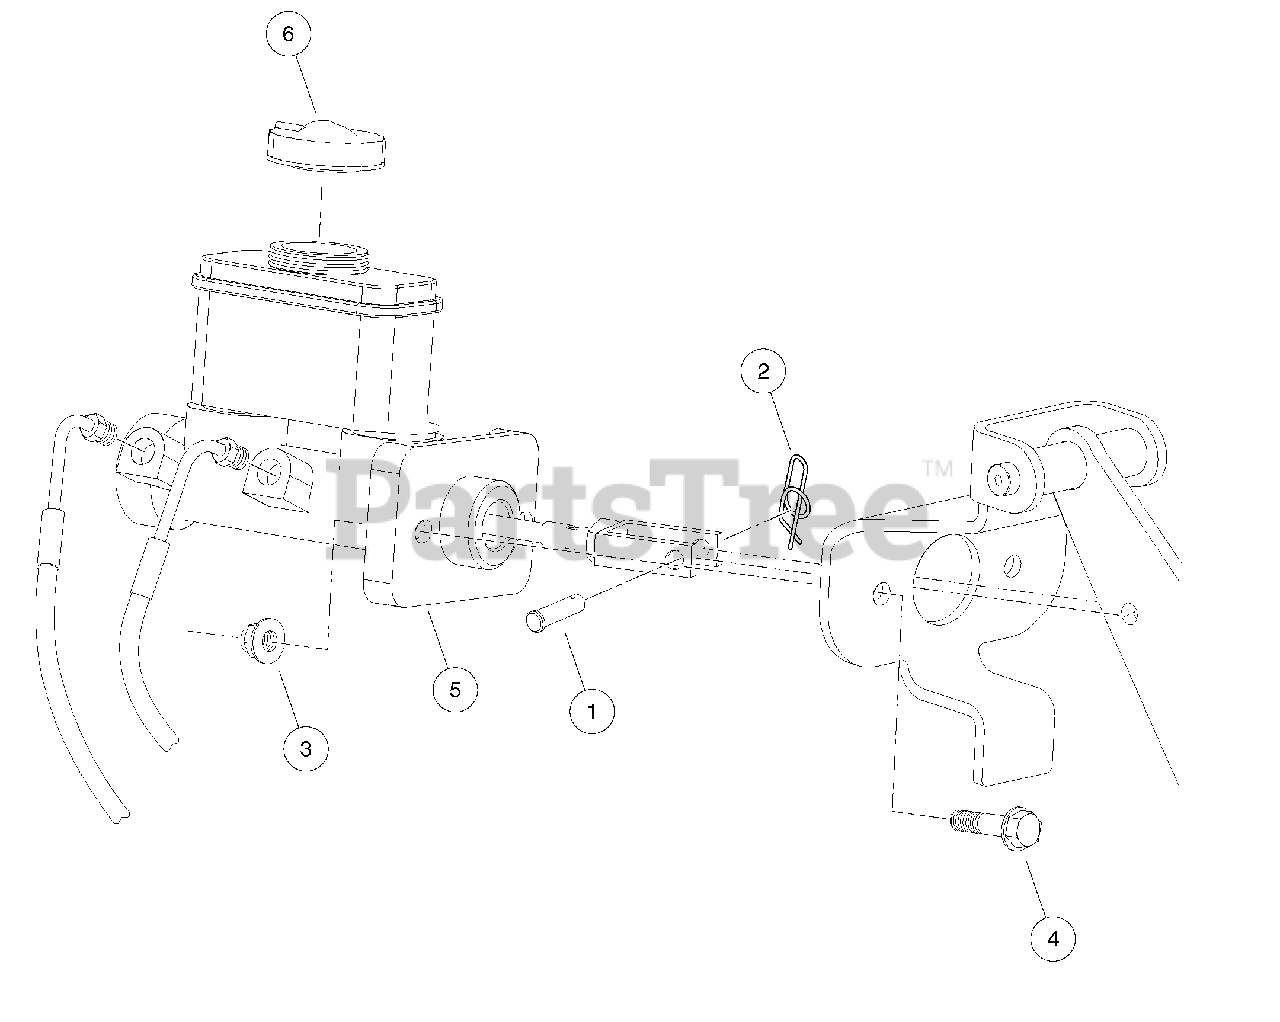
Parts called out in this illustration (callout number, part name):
1	Clevis Pin, 5/16 X 1
3	Nut,m8,all Metal Lock
4	Bolt Flanged Head, M8 X 1.25 X 35
5	Cylinder, Master, Integral Res
6	Filler Cap Asm Integral Res
